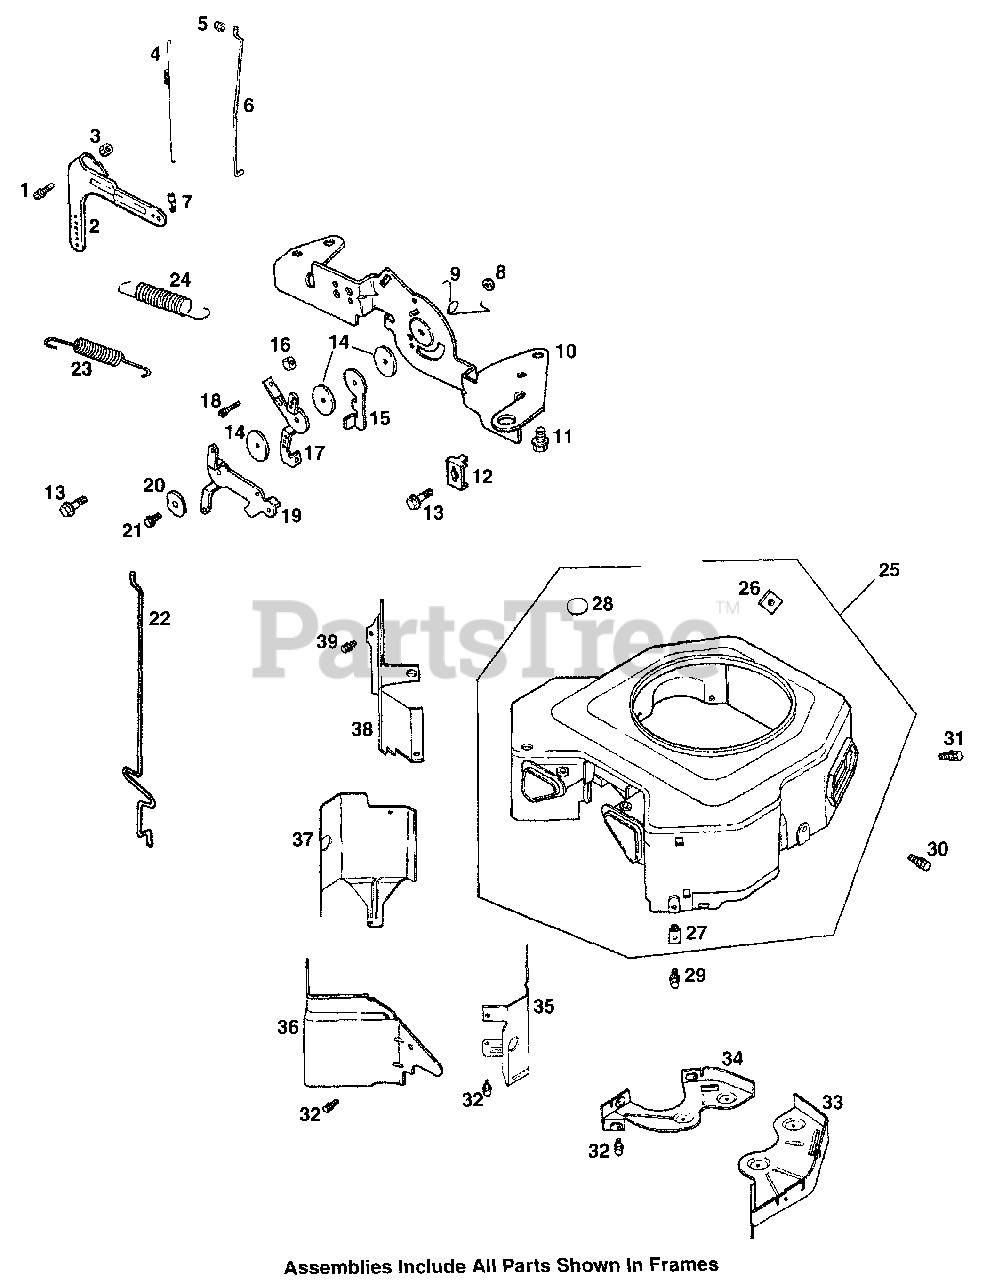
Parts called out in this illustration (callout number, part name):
1	Hex Flange Screw
2	Governor Lever
3	Hex Flange Nut, M6 x 1.0
4	Linkage Spring
5	Linkage Retaining Bushing
6	Throttle Linkage
7	Throttle Linkage Bushing
8	Hex Nut, M5 x.8
9	Choke Return Spring
10	Control Bracket
11	Hex Flange Screw, M6 x 1.0 x 16
12	Cable Clamp
13	Hex Flange Screw, M6 x.8 x 16
15	Throttle Actuator Lever
16	Hex Nut, M4 x.7
17	Throttle Control Lever
18	Hex Cap Screw, M4 x.7 x 25
20	Spring Washer, 1/4"
21	Hex Flange Screw, M5 x.8 x 20
22	Choke Linkage
23	Throttle Limiter Spring
24	Governor Spring
25	Blower Housing
26	Plastic Nut
28	Button Plug, 9/16"
29	Hex Flange Screw, M5 x .8 x 20
30	Hex Flange Screw, M5 x.8 x 16
31	Hex Flange Screw, M5 x.8 x 16
32	Hex Flange Screw, M6 x 1.0 x 16
33	Backing Plate, #2 Side
34	Backing Plate, #1 Side
35	Cylinder Barrel Baffle, #2 Side
36	Valley Baffle, #2 Side
37	Cylinder Barrel Baffle, #1 Side
38	Valley Baffle, #1 Side
39	Hex Flange Screw, M5 x .8 x 10
